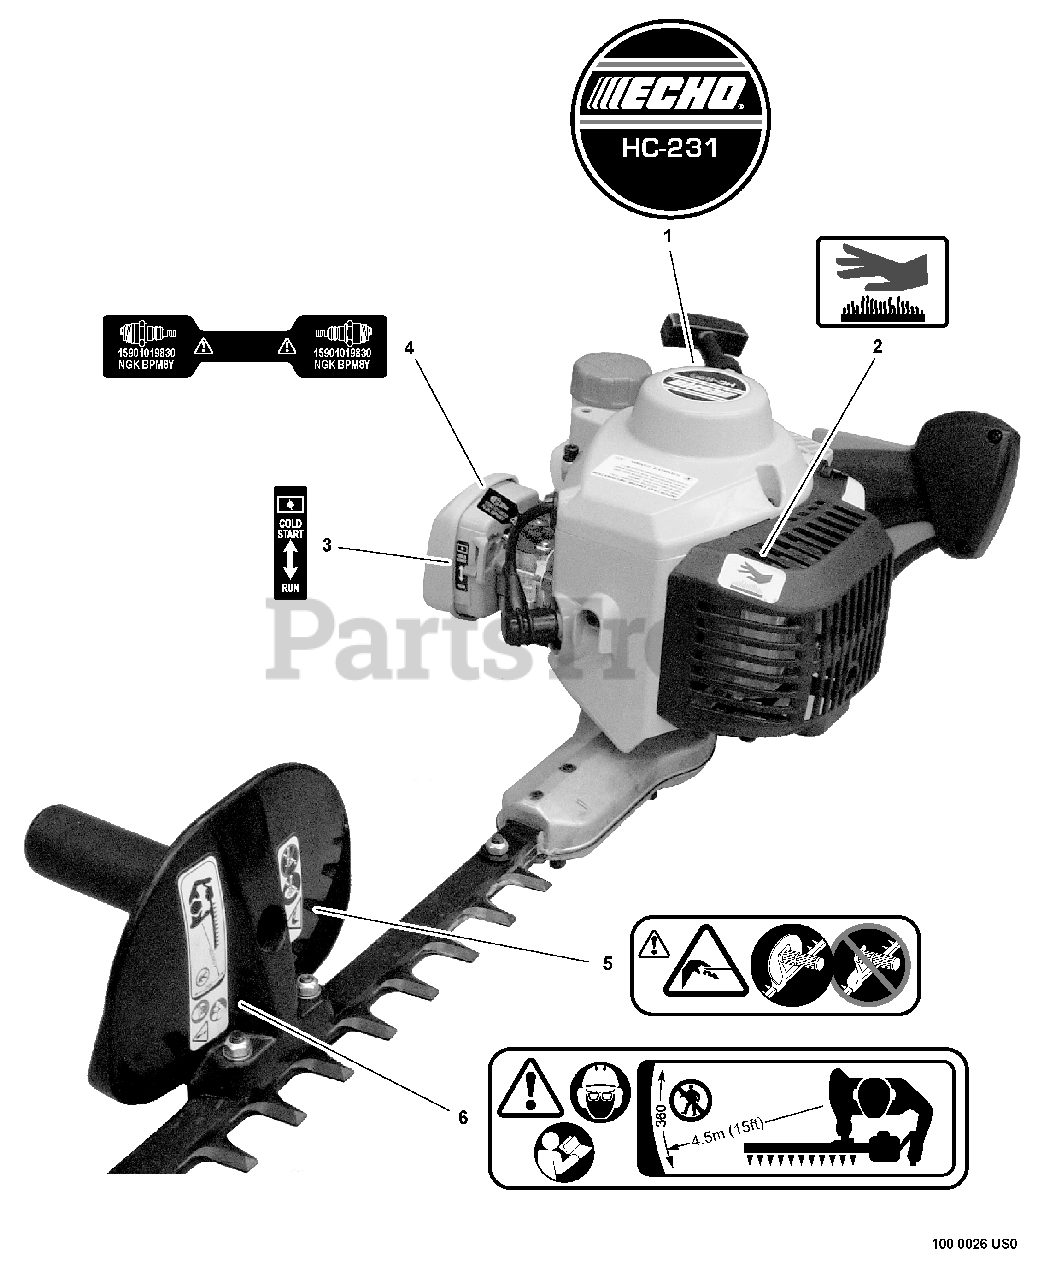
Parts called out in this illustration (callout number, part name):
1	LABEL - MODEL HC-231
2	LABEL - HOT SURFACE
3	LABEL - CHOKE
4	LABEL - SPARK PLUG -- BPM-8Y
5	LABEL - CAUTION
6	LABEL - CAUTION
